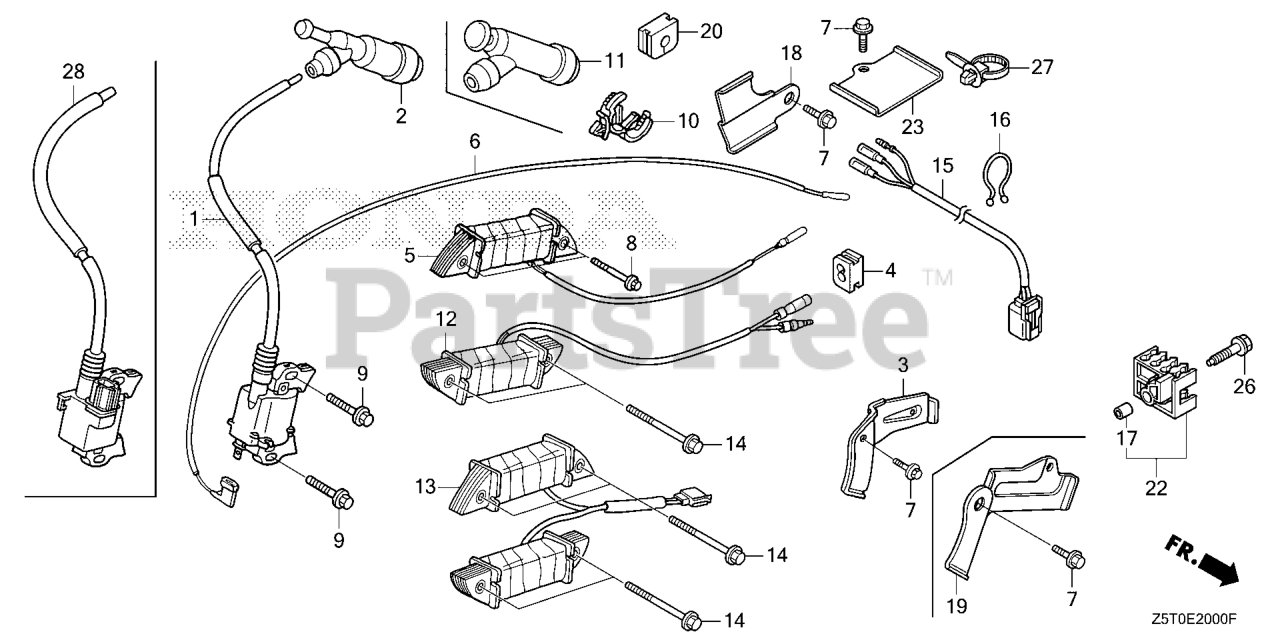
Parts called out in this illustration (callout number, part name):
2	CAP ASSY., NOISE SUPPRESSOR (NGK Y-EZD)
3	CLAMP, WIRE
4	GROMMET, WIRE
7	BOLT, FLANGE (6X12) (CT200)
9	BOLT, FLANGE (6X28) (CT200) Use up to Engine SN 1530314.
13	COIL ASSY., CHARGE (10A)
14	BOLT, FLANGE (6X40)
15	WIRE HARNESS ASSY., ENGINE (SEL)
16	CLIP, PURSE LOCK
28	COIL ASSY., IGNITION
28	COIL ASSY., IGNITION (IIDA)
